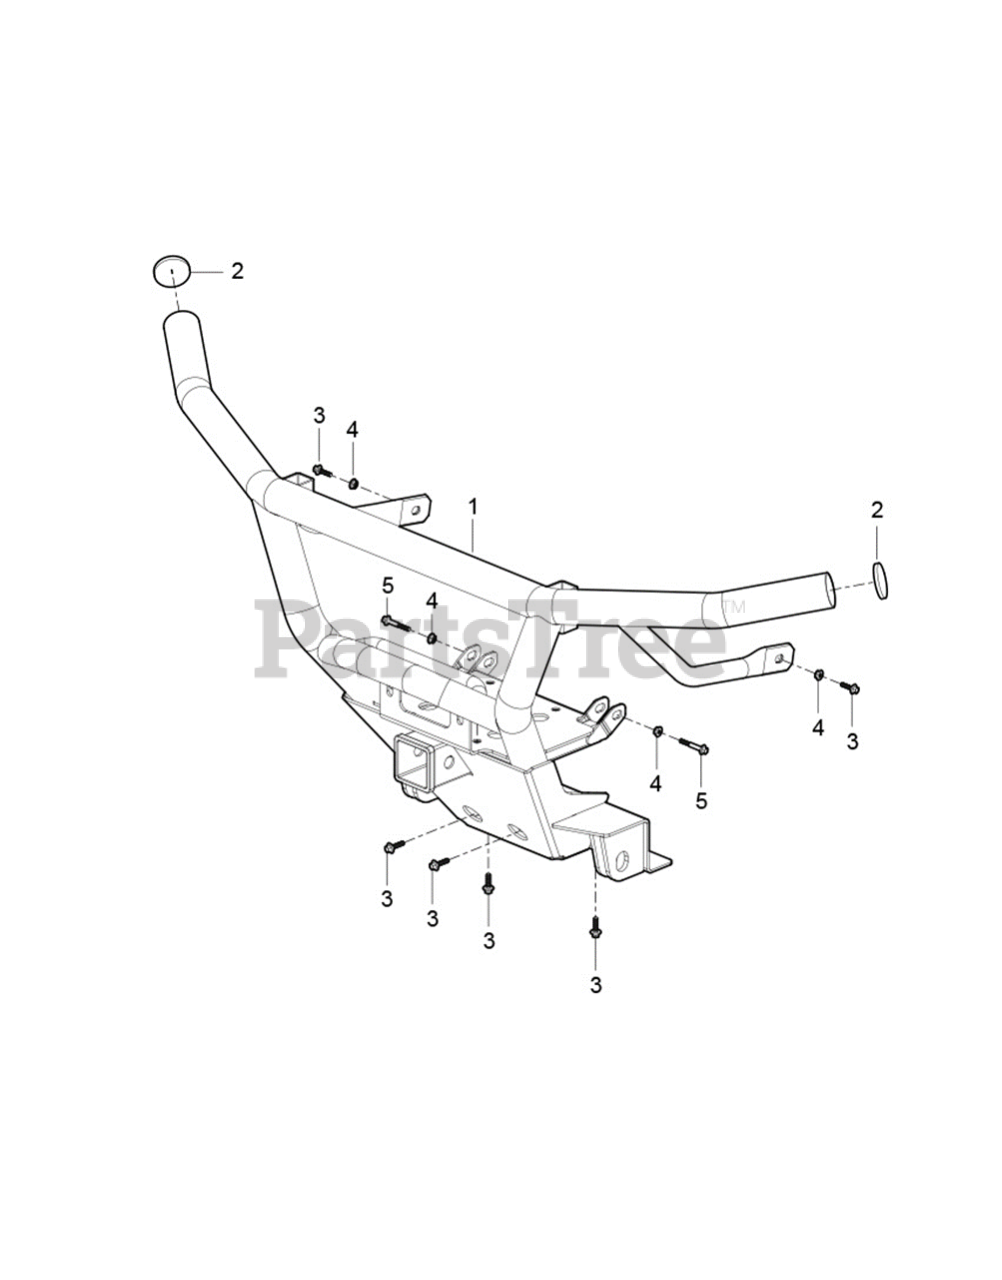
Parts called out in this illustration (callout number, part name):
1	FRONT BUMPER
2	BUMPER TUBE PLUG
3	HEXAGON FLANGE BOLT M10X30
4	LOCK NUT M10X1.25
5	HEX FLANGE BOLT M10X1.25X50
